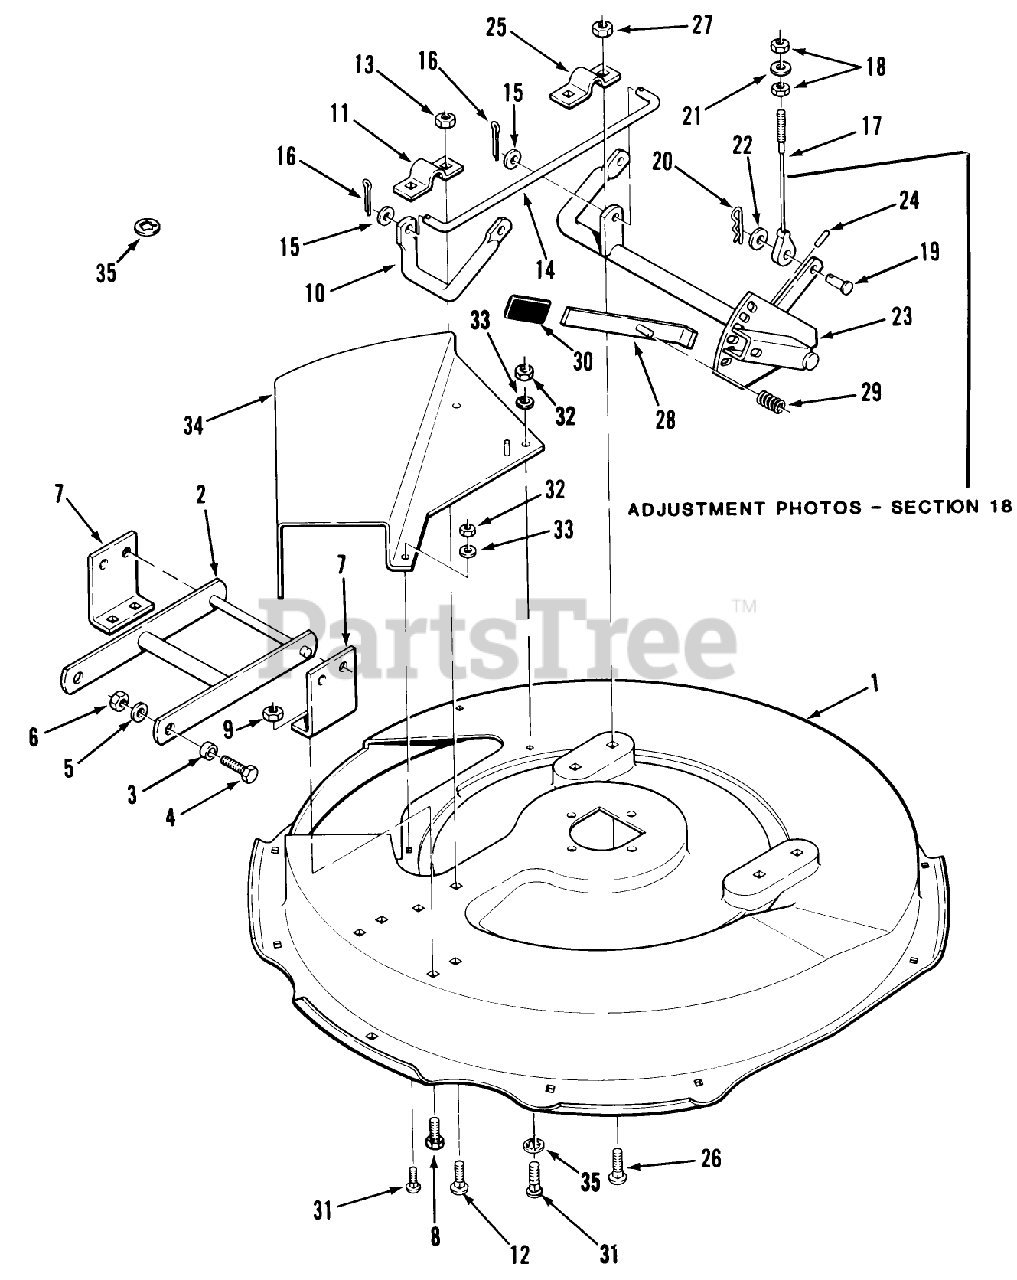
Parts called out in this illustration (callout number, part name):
3	SPACER
7	BRKT FRONT MOWER *R
11	CLAMP
17	CABLE MOWER SUPPORT
20	Hairpin
21	WASHER 5/16 SAE
24	SPIROL PIN
25	CLAMP
28	LEVER ASSY
29	SPRING-COMPRESSION
